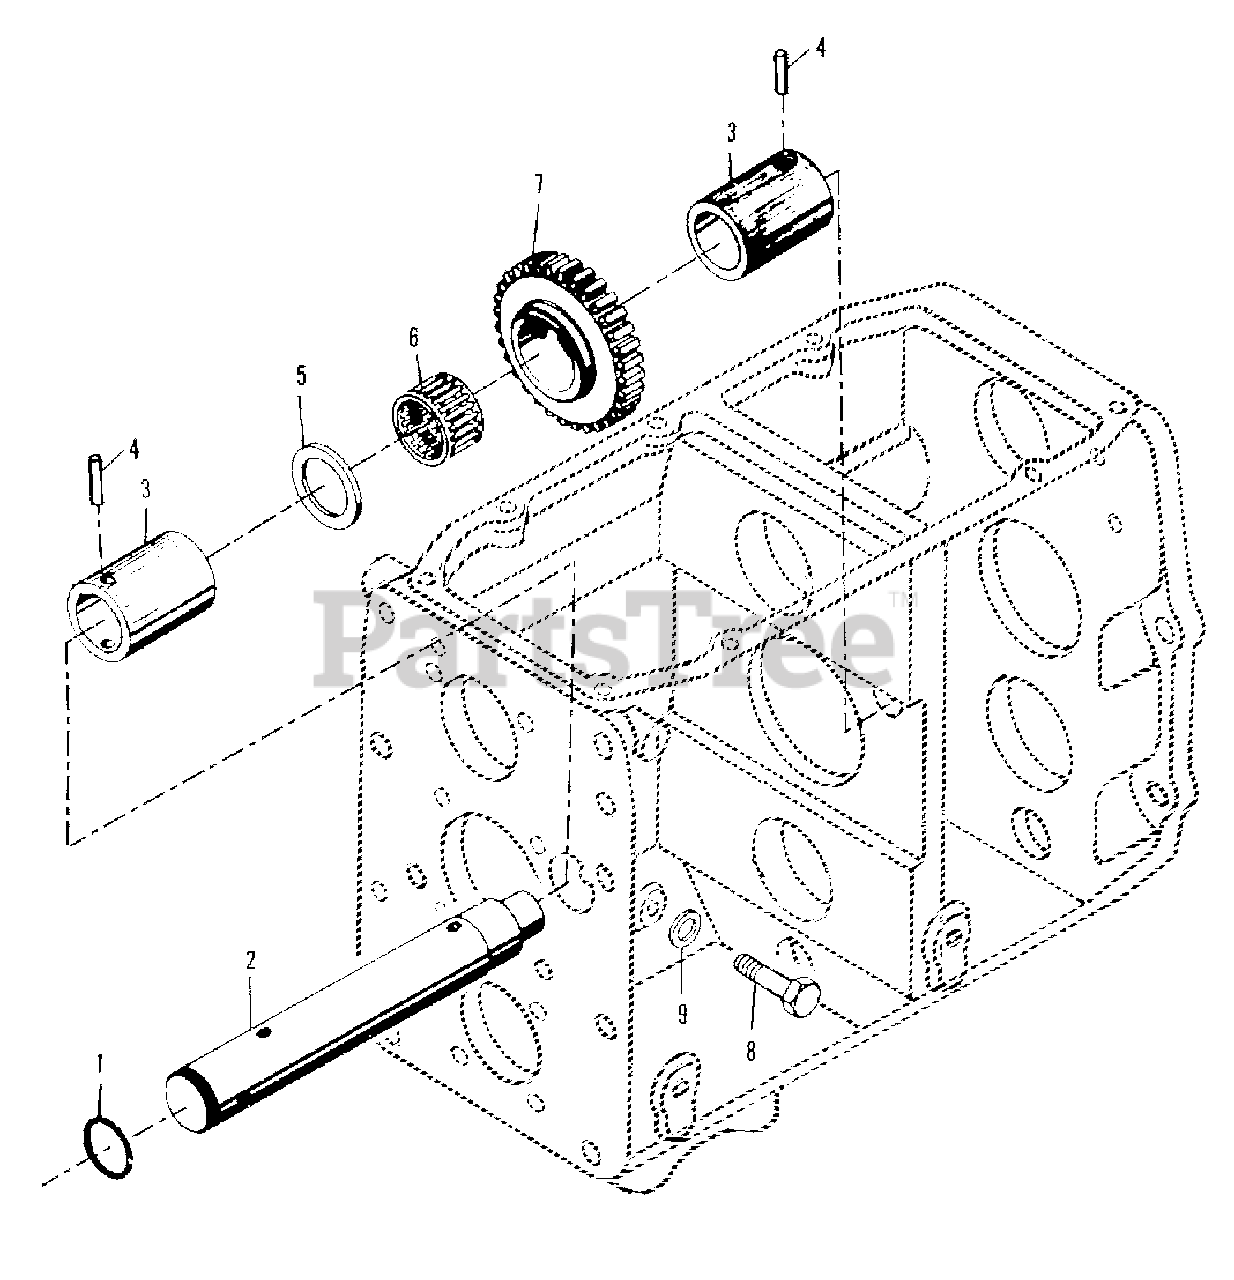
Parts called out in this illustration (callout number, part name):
2	SHAFT, reverse-idler
3	COLLAR, distance-reverse idler shaft
4	PIN, M16 x 18 lock
5	WASHER, thrust (2.9)
5	WASHER, thrust (3.2) (Select one)
5	WASHER, thrust (3.5)
6	BEARING, needle
7	GEAR, reverse - idler
8	SCREW, lock
9	WASHER, seal
